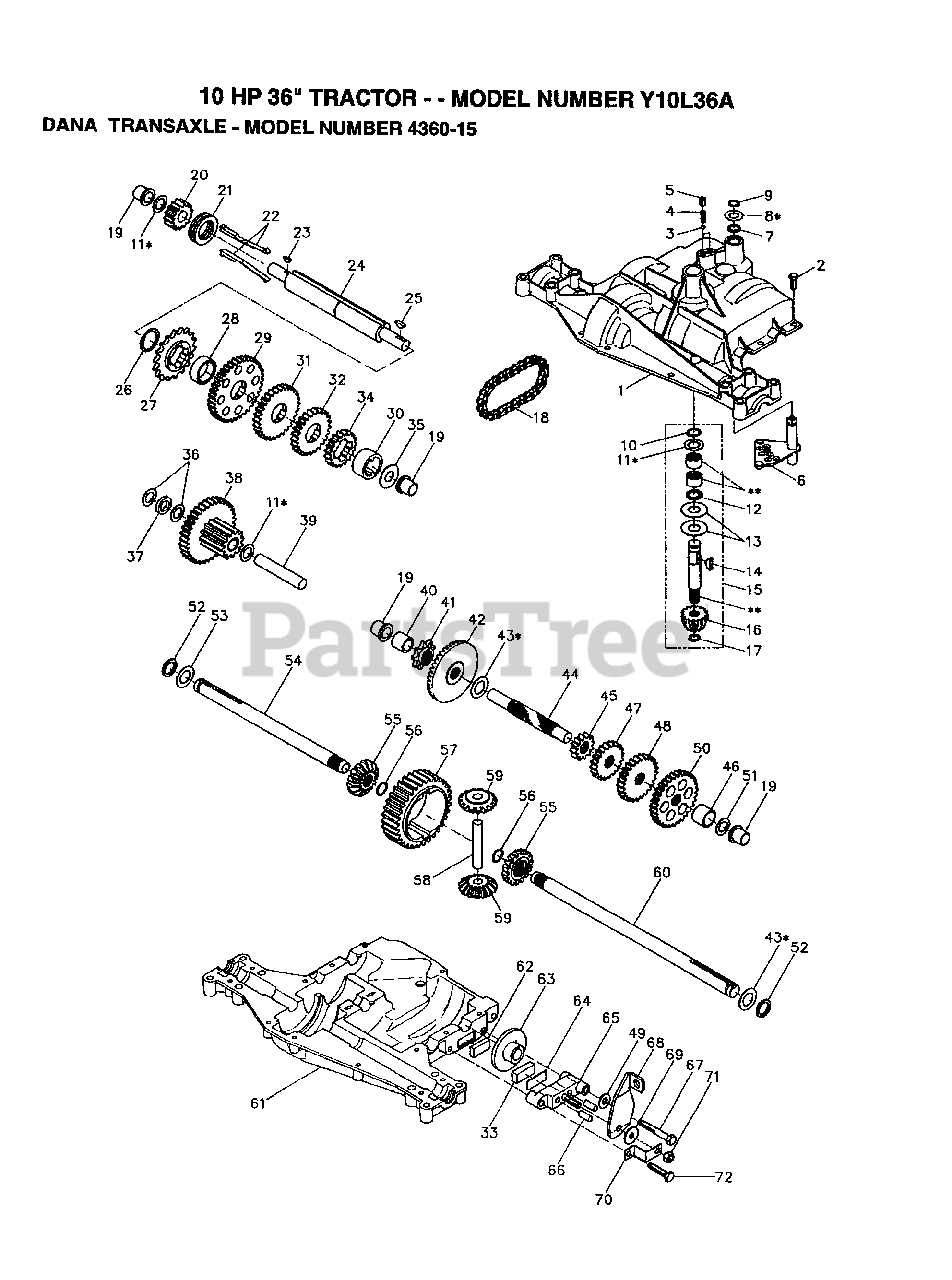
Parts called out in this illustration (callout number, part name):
1	HOUSING UPPER
3	BALL DETENT
4	SPRING, DETENT
5	SCREW, SET
6	ASSY SHIFTER
8	WASHER PLAIN
8A	WASHER PLAIN
8B	WASHER PLAIN
8C	WASHER PLAIN
8D	WASHER PLAIN
8E	WASHER PLAIN
8F	WASHER PLAIN
9	RING RETAINING
10	RING RETAINING
11	WASHER PLAIN
11A	WASHER PLAIN
11B	WASHER, PLAIN .632 X 1.00 X .026
11C	WASHER PLAIN
11D	WASHER PLAIN
11E	WASHER PLAIN
11F	WASHER PLAIN
11G	WASHER PLAIN
11H	WASHER, PLAIN .632 X 1.00 X .060
11I	WASHER PLAIN
13	WASHER, PLAIN .632 X 1.38 X .046
14	KEY WOODRUFF #9
15	ASSY KIT INPUT SHAFT
16	PINION, BEVEL, 14 TEETH
17	RING, RETAINING
18	CHAIN, 24 PITCHES
19	BEARING, FLANGE
20	GEAR SPUR, 14 TEETH
21	COLLAR CLUTCH
22	KEY CLUTCH
23	KEY WOODRUFF #3
24	SHAFT INTERMEDIATE
25	KEY, WOODRUFF, #61
26	RING, RETAINING
27	SPROCKET, 18 TEETH
29	GEAR, SPUR, 37 TEETH
31	GEAR, SPUR, 30 TEETH
32	GEAR, SPUR, 25 TEETH
33	PUCK, FRICTION
35	WASHER, PLAIN .640 X 1.37 X .061
36	WASHER, PLAIN .632 X 1.00 X .026
37	SPACER .630 X 1.00 X .169
38	ASSY GEAR COMB 12&35 TEETH
39	SHAFT IDLER
40	SPACER .635 X .875 X .755
41	SPROCKET, 9 TEETH
42	GEAR, BEVEL, 42 TEETH
43	WASHER PLAIN
43A	WASHER PLAIN
43B	WASHER PLAIN
43C	WASHER PLAIN
43D	WASHER PLAIN
43E	WASHER PLAIN
43F	WASHER, PLAIN .758 X 1.25 X .031
43G	WASHER PLAIN
43H	WASHER PLAIN
43I	WASHER PLAIN
43J	WASHER PLAIN
43K	WASHER PLAIN
43L	WASHER PLAIN
44	SHAFT, DRIVE
45	GEAR, SPUR, 12 TEETH
46	SPACER .781 X 1.00 X .750
47	GEAR, SPUR, 20 TEETH
48	GEAR, SPUR, 25 TEETH
49	WASHER PLAIN
50	GEAR, SPUR, 31 TEETH
51	WASHER, PLAIN .632 X 1.00 X .060
53	WASHER PLAIN
54	AXLE LEFT HAND
55	GEAR, MITER, 15 TEETH
56	RING, RETAINING
57	GEAR, SPUR, 32 TEETH
58	SHAFT, CROSS
59	GEAR, MITER, 15 TEETH
60	AXLE RIGHT HAND
61	HOUSING LOWER
62	PUCK, FRICTION
63	DISC, BRAKE
65	JAW, BRAKE
66	PIN, DOWEL
67	SCREW TAPPING
68	LEVER, ACTUATING
69	WASHER, PLAIN .321 X 1.00 X .055
70	BRACKET, ANTI-ROTATION
71	LOCKNUT 5/16-24
72	SCREW TAPPING
